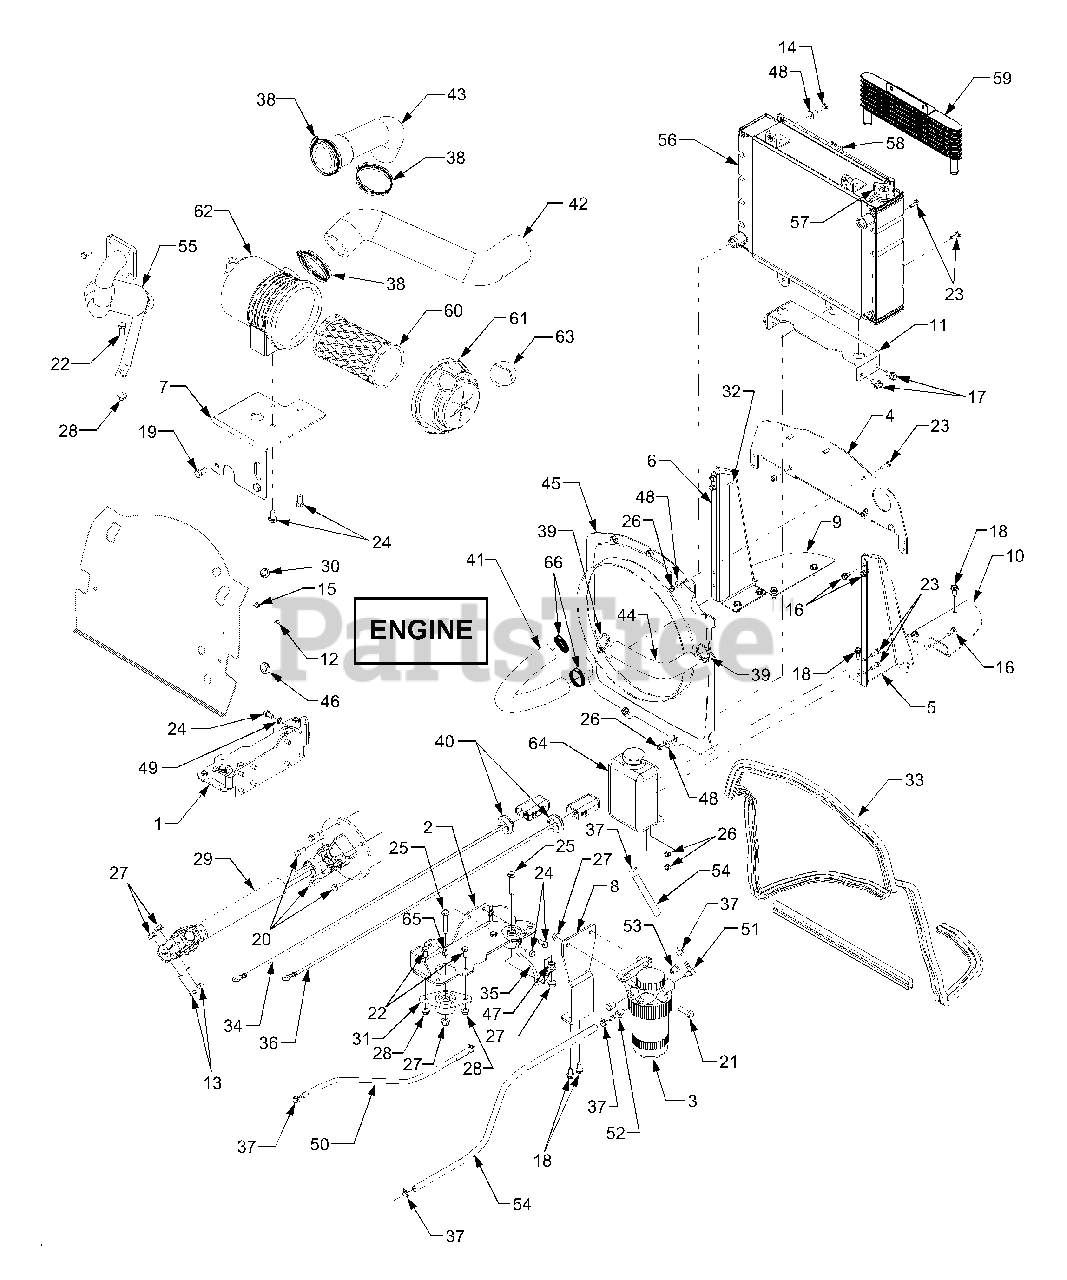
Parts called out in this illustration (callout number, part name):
1	Bracket, Engine LH
2	Bracket, Engine RH
3	Filter Assembly, Fuel
4	Plate, Radiator Baffle
5	Bracket, Radiator Mtg. RH
6	Bracket, Radiator Mtg. LH
7	Bracket, Air Cleaner Mtg.
10	Plate, Baffle, RH
11	Bracket, Radiator Mtg.
12	Screw, Hex Wash Hd Tapp 10-16 x .5
13	Screw, Hex Cap 3/8-16 x 1.75 GR5
14	Screw, Hex Cap 1/4-20 x 1.0 GR5
15	Screw, Hex Wash Hd Tapp 1/4-20 x .5
16	Screw, Hex Wash Hd Tapp 5/16-18 x .5
17	Screw, Hex Wash Hd Tapp 3/8-16 x .75
18	Screw, Hex Wash Hd Tapp 5/16-18 x .75
19	Screw, Hex Cap, M8-1.25 x 16
20	Screw, Hex Cap, M8-1.25 x 20
21	Screw, Hex Cap, 3/8-16 x 1/25 GR5
22	Screw, Hex Cap 5/16-18 x .75 GR5
23	Screw, Hex Cap 1/4-20 x .75 GR5
24	Screw, Hex Cap,l M8-1.25 x 16
25	Screw, Hex Cap 3/8-16 x 2/0 GR5
26	Nut, Hex Insert Lock, 1/4-20
27	Nut, Hex Flange Lock, 3/8-16
28	Nut, Hex Flange Lock, 5/16-18
29	Shaft, Drive
30	Plug, Cap
31	Mount, Neoprene Engine
32	Tape, Foam, .625 wide
33	Seal, Heat Baffle
34	Wire, Battery Pos.
35	Wire, Ground
36	Wire, Battery Neg.
37	Clamp, Hose
38	Clamp, Adjustable Hose
39	Clamp, Hose
40	Grommet, Hose Guard
41	Hose, Radiator to Engine
42	Hose, Air Filter
43	Hose, Air Inlet
44	Hose, Engine to Radiator
45	Shroud, Fan
46	Grommet, Rubber
47	Washer, External Lock, 3/8
48	Washer, Flat, .28 x .74 x .063
49	Washer, External Lock, 5/16
50	Hose, Fuel Line
51	Fitting, 90 Degree Hose
52	Fitting, Straight Hose
53	Plug, Drain
54	Fuel Line, 5/16 ID
55	Muffler, Engine
57	Cap, Radiator, 13psi
58	Screen, Debris
59	Cooler, Oil
60	Element, Air Cleaner
61	Cap, Air Cleaner
62	Cannister, Air Cleaner
63	Nozzle, Air Cleaner
64	Bottle, Overflow
65	Screw, Hx Cap, M8-1.25:25 GR8
66	Clamp, Hose
